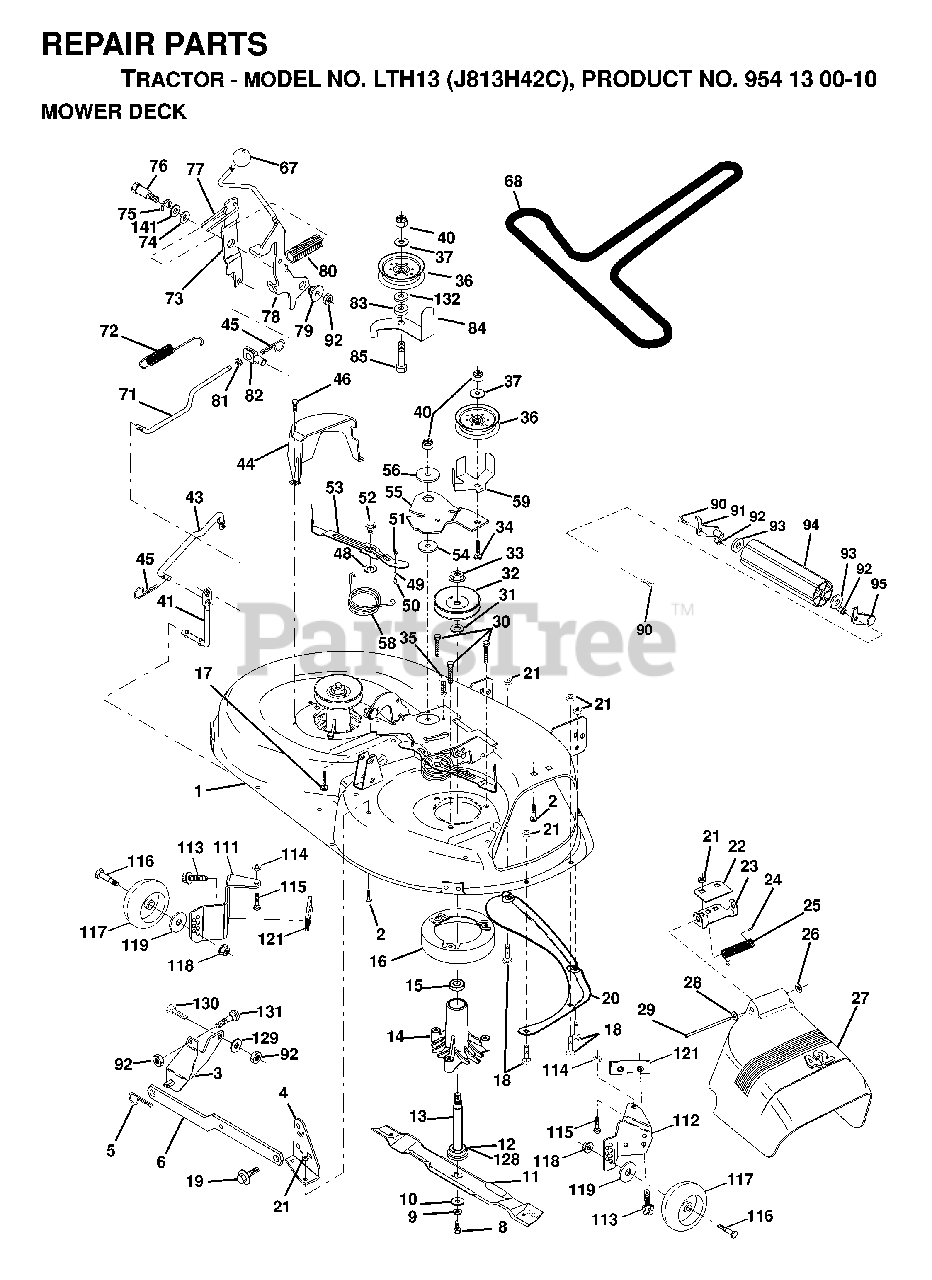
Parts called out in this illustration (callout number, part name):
1	DECK 42"
2	BOLT
3	BRKT ASM SWAY BAR
4	BRKT DECK SW BAR
5	RETAINER-SPRNG RB
6	REAR SUSP ARM
8	BLADE BOLT
9	LOCKWASHER
10	WASHER.BLADE
12	BEARING
13	SHAFT ASM VENT
14	HSG MANDREL
16	STRIPPER
17	BOLT
18	BOLT
19	BOLT SHD 5/16-18
20	BAFFLE
21	LOCKNUT
22	STIFFENER BRACKET
23	DEFLECTOR BRACKET
24	CAP-SLEEVE LT
25	SPRING TORSION
26	NUT PUSH M
27	SHIELD.DEFLECTOR.MOWER.42".BLK
28	WASHER
29	ROD.HINGE
30	SCREW THDROL ROLLING WASHER HD
31	WASHER
32	PULLEY/MANDREL
33	NUT
34	BOLT
35	FASTENER.XMAS.TREE
36	FLAT IDLER PULLEY
40	LOCKNUT
41	PIVOT ROD
43	CLUTCH ROD
44	GUARD MANDREL LH BLACK
45	RETAINER M
46	SCREW.1/4-20X5/8
49	ROLLER ASSY
50	BOLT
53	ARM
54	HARDENED WASHER
55	ARM IDLER 42" MOWER LT/YT
56	SPACER RETAINER
59	GUARD, BELT
67	KNOB.CONTROL.7/16
71	CLUTCH ROD
72	RETURN SPRING
73	ARM CLUTCH SECONDARY
75	RING CLIP
77	KEEPER SPRING
78	CLUTCH LEVER ASSY
79	BUSHING.FLANGE.E-RING.GROOVE
80	SPRING-CLUTCH
81	NUT
84	KEEPER.BELT.IDLER
85	BOLT
90	BOLT
91	BRACKET LH (A)
92	NUT
94	NOSE ROLLER
95	BRACKET RH (B)
111	BRACKET WHEEL GAUGE LH 42" DK
112	BRACKET WHEEL GAUGE RH 42" DK
113	SCREW
114	NUT
115	BOLT
118	LOCKNUT
119	WASHER
121	BRACKET.EXTRD.GWL
128	WASHER FELT
129	WASHER
131	BOLT D
132	WASHER GT
